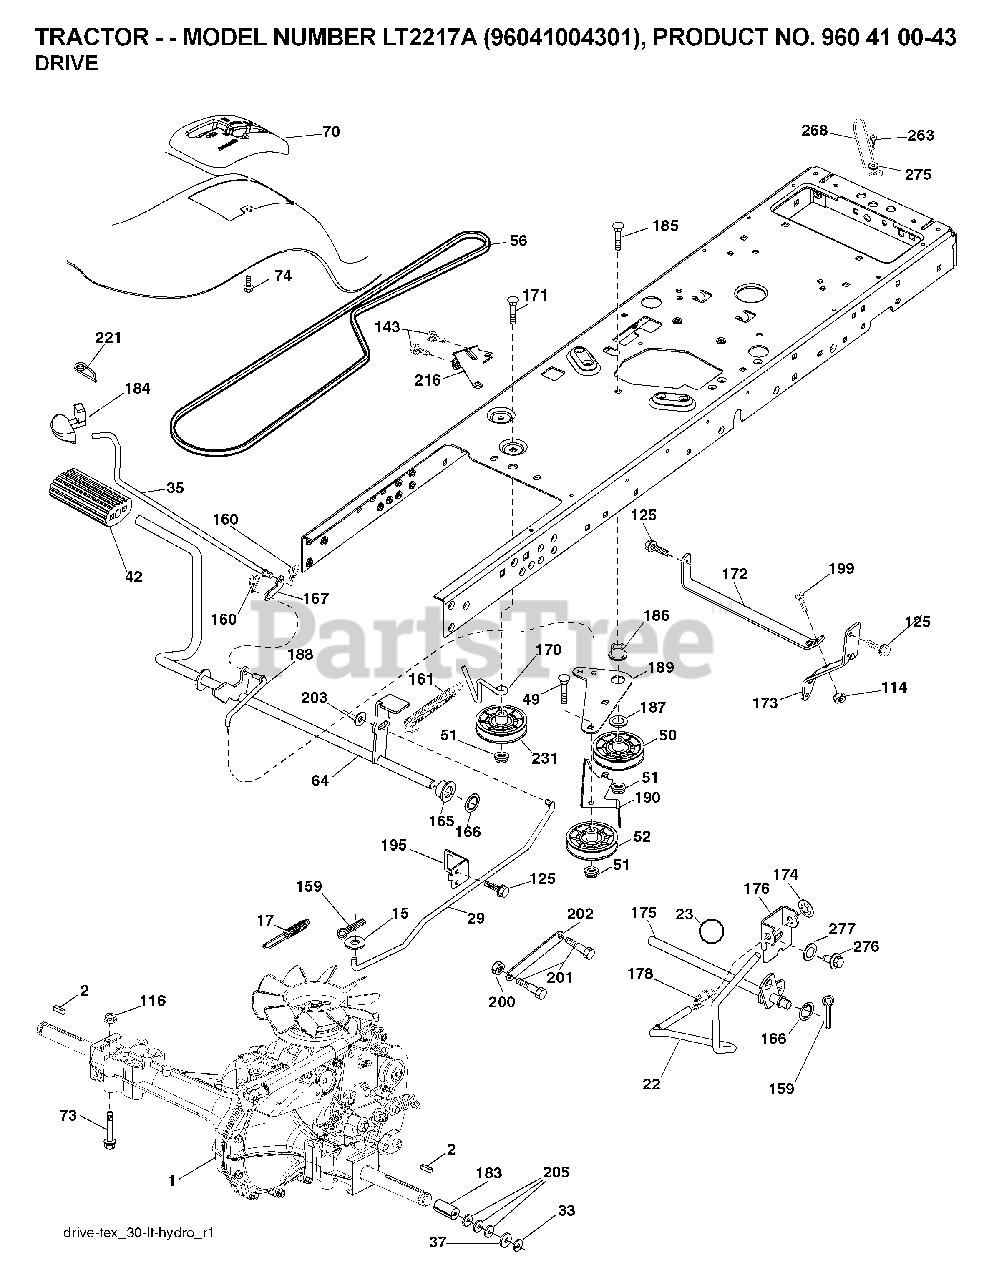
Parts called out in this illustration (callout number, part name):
2	SQUARE KEY
17	SPRING.BRAKE.HG3000/3500
22	ROD.SHIFT.FENDER.TLT.2006
23	KNOB.DUCKHEAD.1/2
29	ROD.BRAKE.HG-0510
33	E-RING LT
35	ROD.BRAKE.PARKING.LT.T
42	PEDAL COVER T
49	BOLT
50	IDLER.FLAT.910.OFFSET
51	NUT LOCK FLG 3/8-16 UNC
52	IDLER.V-GROOVE.910.OFFSET
64	SHAFT.ASM.PEDAL.BRAKE.
70	CONSOLE.SHIFT.STL.HYD.BLACK
73	BOLT HEX 5/16-18 GR 5
74	SCREW.HI-LO.CONSOLE
114	NUT.71038.31-18.HEX.NYLOCK
116	NUT LOCK HEX FLANGE 5/16-18
125	SCREW
159	COTTER PIN
160	RETAINER CLIP
165	BUSHING.SHAFT.BRAKE.HAND
166	NUT.PUSH.625.2006
167	LATCH.BRAKE.SPRING
170	KEEPER.V-IDLER.CENTER.
172	STRAP.TRQ.LH.FS.HG0510
173	STRAP TORQUE RH
174	NUT.PUSH.500.2006
175	SHAFT.ASM.SHFT.HG0510/
176	ARM.CLEVIS.ROD.SHIFT
178	SPRING.SHIFT.GT2006
183	SPACER AXLE
184	HANDLE.PAKRING.BRAKE.
186	SPACER.RETAINER
187	WASHER 12/32X2X10GA
188	LINK.CLUTCH.GROUND.DRIVE
189	BELLCRANK.GROUND.DRIVE.TEX.
190	KEEPER.BELLCRANK.DRIVE
195	BRKT.ROD.BRAKE.18/20/2
199	BOLT
200	NUT.CENTERLOCK.5/16-
201	BOLT SHOULDER 5/16-18 UNC
202	LINK TRANS
203	WASHER
216	BRACKET.PULLEY.IDLER.W/TEX
221	RETAINER.SPRING.CLIP.H
231	IDLER.V-GROOVE.1.688.OFFSET
263	SCREW, 3/8-16X3/4
275	WASHER
276	BOLT FIN HEX 7/16-14 X 1
277	WASHER SERRATED
